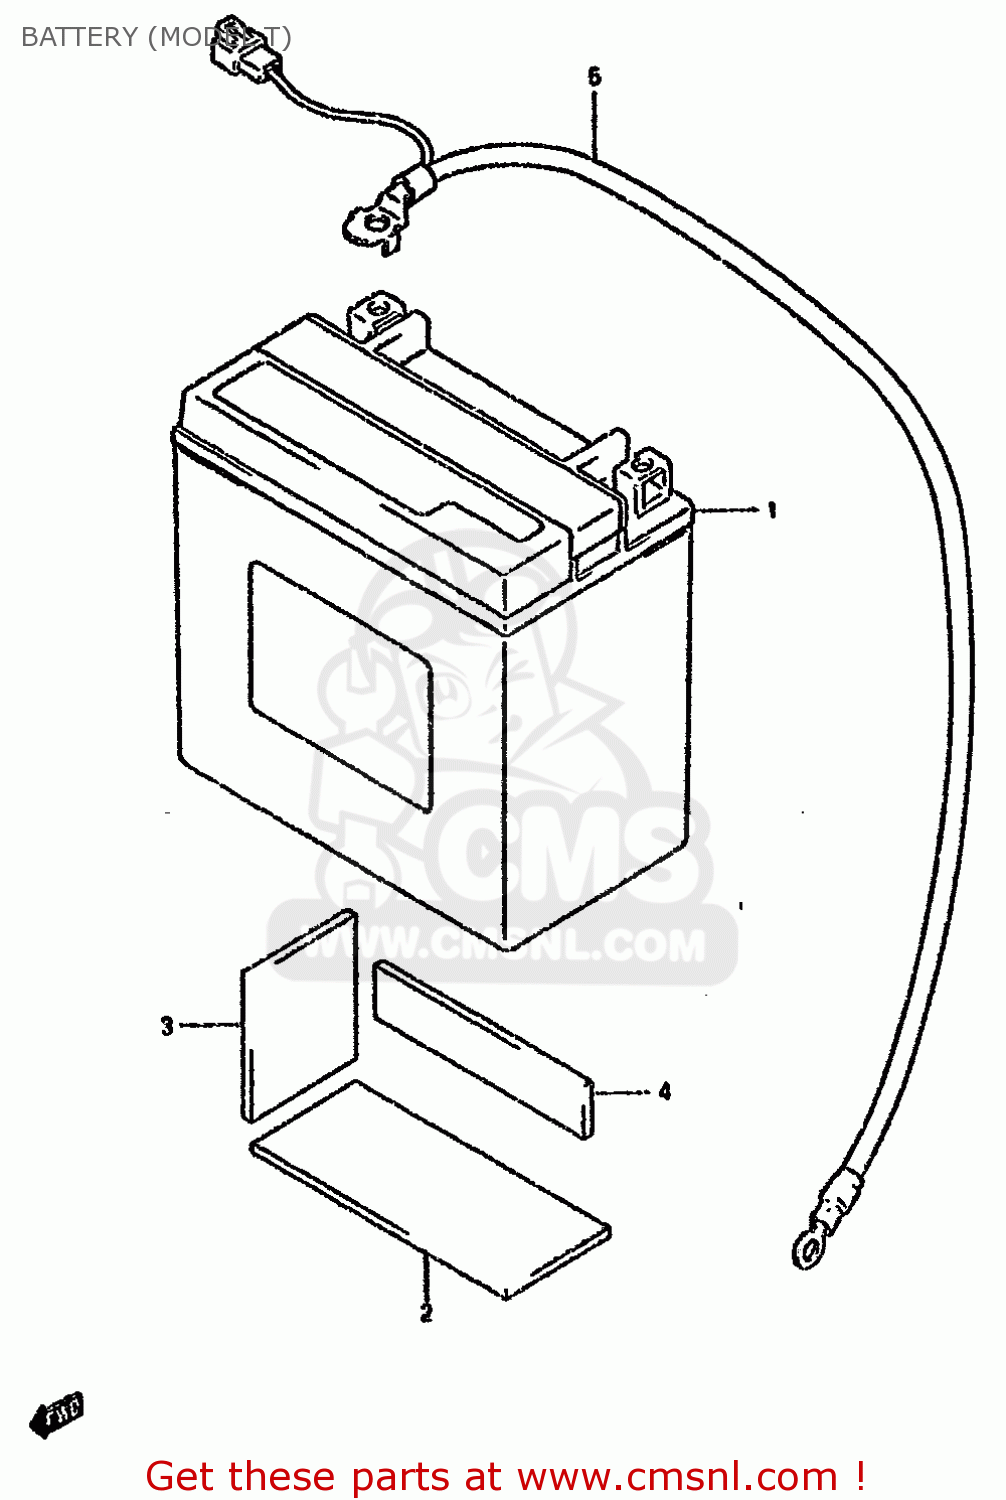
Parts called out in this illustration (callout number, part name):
1	BATTERY ASSY (12V) YTX14-BS
2	PROTECTOR(170X95X3.0)
3	PROTECTOR(170X95X3.0)
4	PROTECTOR,20X9
5	WIRE,BATTERY MINUS LEAD
